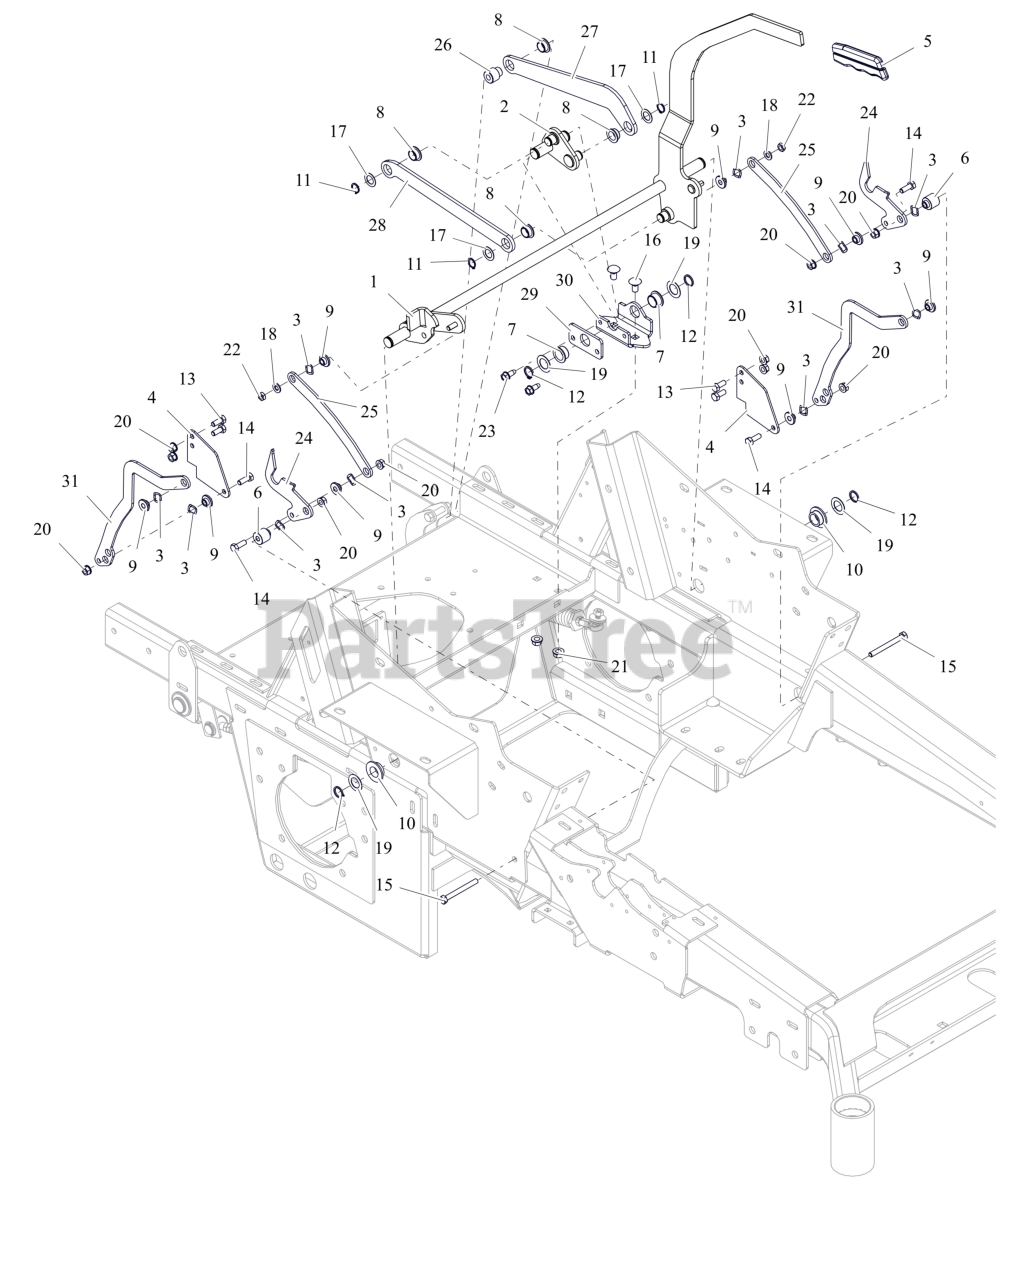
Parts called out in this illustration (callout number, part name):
1	WLDMT, PARKING BRAKE ARM (BLACK)
2	WLDMT, BRAKE ACTIVATION PIVOT
3	WAVE WASHER .531X.781X.125FH
4	BRKT, HTJ SPEED CONTROL
5	GRIP, PARKING
6	BUSHING FLANGED - .318X.500X.972X.875
7	BSHG, FLANGE .750 X .875 X .5000 X 1.125
8	BSHG, FLANGE .625 X .750 X .375 X 1.000
9	BSHG-FLG .32X.500X.344X.880
10	BSHG-FLG .762X1.48X.44 NYL
11	RG-RTNG-EXT .625X.050
12	RG-RTNG-EXT .689X.078
13	BLT,HEX .31-18X.75 G5 ZCC
14	BLT, HEX .31-18X.875 G5 ZCC
15	BLT, HEX .31-18X3.00 G5 ZCC
16	BLT, RHSN .38-16X.750 G5 ZCC
17	WSHR-THRST .625 X 1.0 X .03
18	WSHR,FLT .344X.688X.065 ZCC
19	WSHR-HDND-THRST .758X1.23X.031
20	NUT,LK-CTR-FLG .31-18 GF ZCC
21	NUT-LK-CTR-FLG .375-16 GF ZCC
22	NUT-LK-CTR-JAM .312-18 GB ZCC
23	SCR,TAP .312-18X.75 HWH TR ZCC
24	BRKT, BRAKE - RTN (BLACK)
25	BRKT, LINK - BREAK RTN (BLACK)
27	LINK, BRAKE ACTIVATION REAR
28	LINK, BRAKE ACTIVATING FRONT
29	PLATE, BSHG MOUNTING
30	BRKT, BSHG MTG
31	LINK- SPEED CONTROL -HTJ (BLK)
